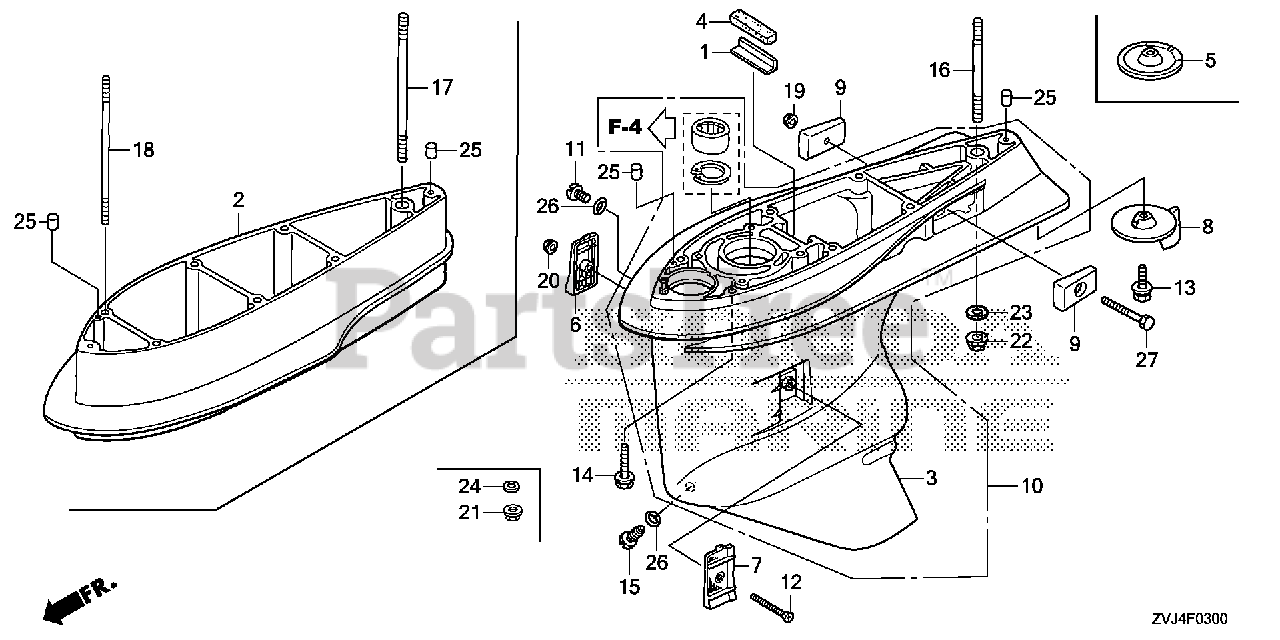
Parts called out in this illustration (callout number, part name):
1	PLATE, RUBBER SETTING
2	SEPARATOR, EXTENSION *NHB14M* (AQUA MARINE SILVER METALLIC)
2	SEPARATOR, EXTENSION *NH565* (GRAND PRIX WHITE)
3	CASE, GEAR *NHB14M* (AQUA MARINE SILVER METALLIC)
3	CASE, GEAR *NH565* (GRAND PRIX WHITE)
4	GROMMET, GEAR CASE
5	COVER, GEAR CASE *NHB14M* (AQUA MARINE SILVER METALLIC)
5	COVER, GEAR CASE *NH565* (GRAND PRIX WHITE)
6	SCREEN, R. WATER
7	SCREEN, L. WATER
9	METAL, ANODE
10	CASE, GEAR *NHB14M* (AQUA MARINE SILVER METALLIC)
10	CASE, GEAR *NH565* (GRAND PRIX WHITE) (NOT AVAILABLE)
11	BOLT, OIL CHECK
12	SCREW, FLAT (5X55)
13	BOLT-WASHER (10X32)
15	BOLT, DRAIN PLUG
17	BOLT, STUD (12X170)
18	BOLT, STUD (10X170)
19	NUT, SELF-LOCK (6MM)
20	NUT, SELF-LOCK (5MM)
21	NUT, SELF-LOCK (10MM)
22	NUT, SELF-LOCK (12MM)
23	WASHER, PLAIN (12MM)
24	WASHER, PLAIN (10MM)
25	PIN, DOWEL (6X10)
26	O-RING (6.9X1.45)
27	BOLT, HEX. (6X55)
